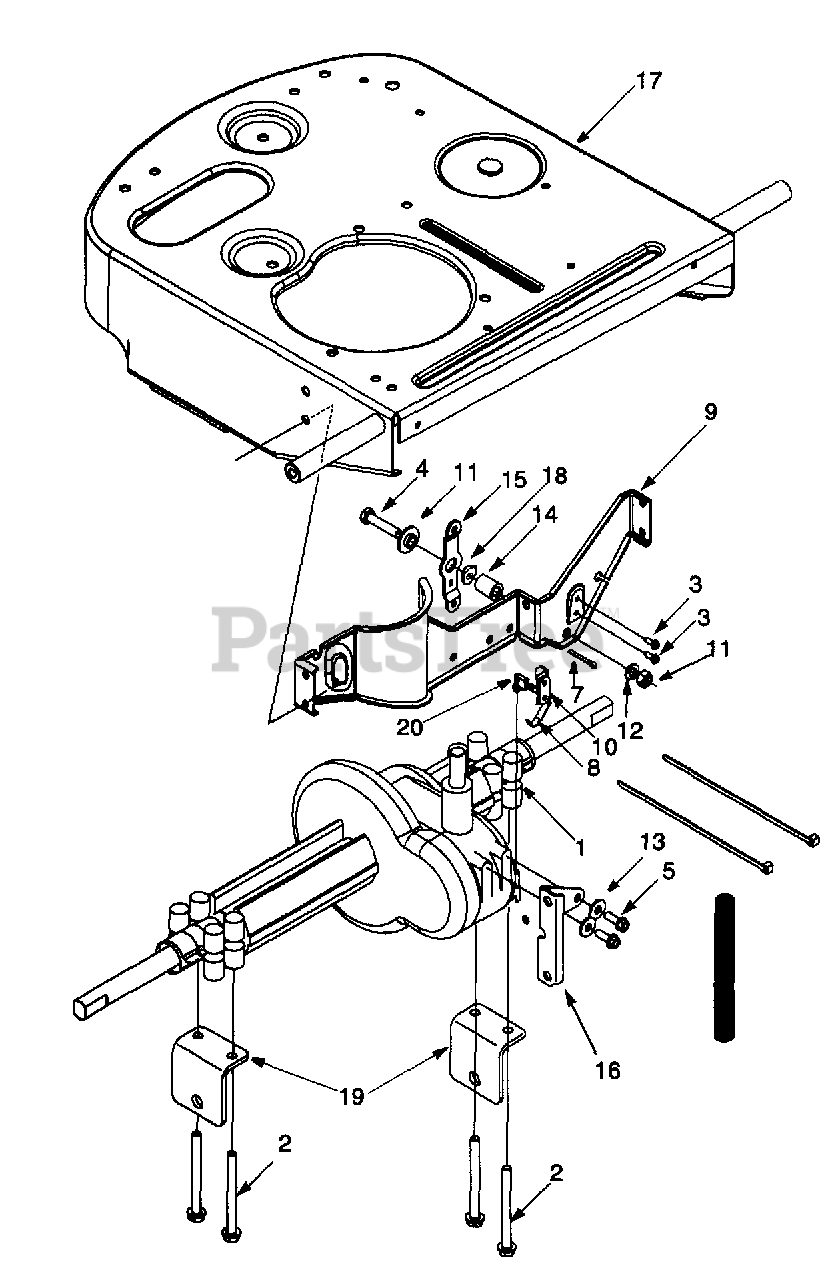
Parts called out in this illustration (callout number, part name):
1	Harness Assembly Adapter
2	Hex TT Screw 5/16-18 x 3.50
3	Hex Washer Head Self-Tap. Screw
4	Hex Screw 5/16-18 x 1.5 Gr. 5
5	Thd. Forming Scr. 1/4-20 x .75
7	Cotter Pin
8	Insulator Nut Plate
11	Shoulder Bushing
12	Lock Washer 5/16
13	Flat Washer .28 I.D. x.74 O.D. x.083
14	Spacer
15	Shift Lever
